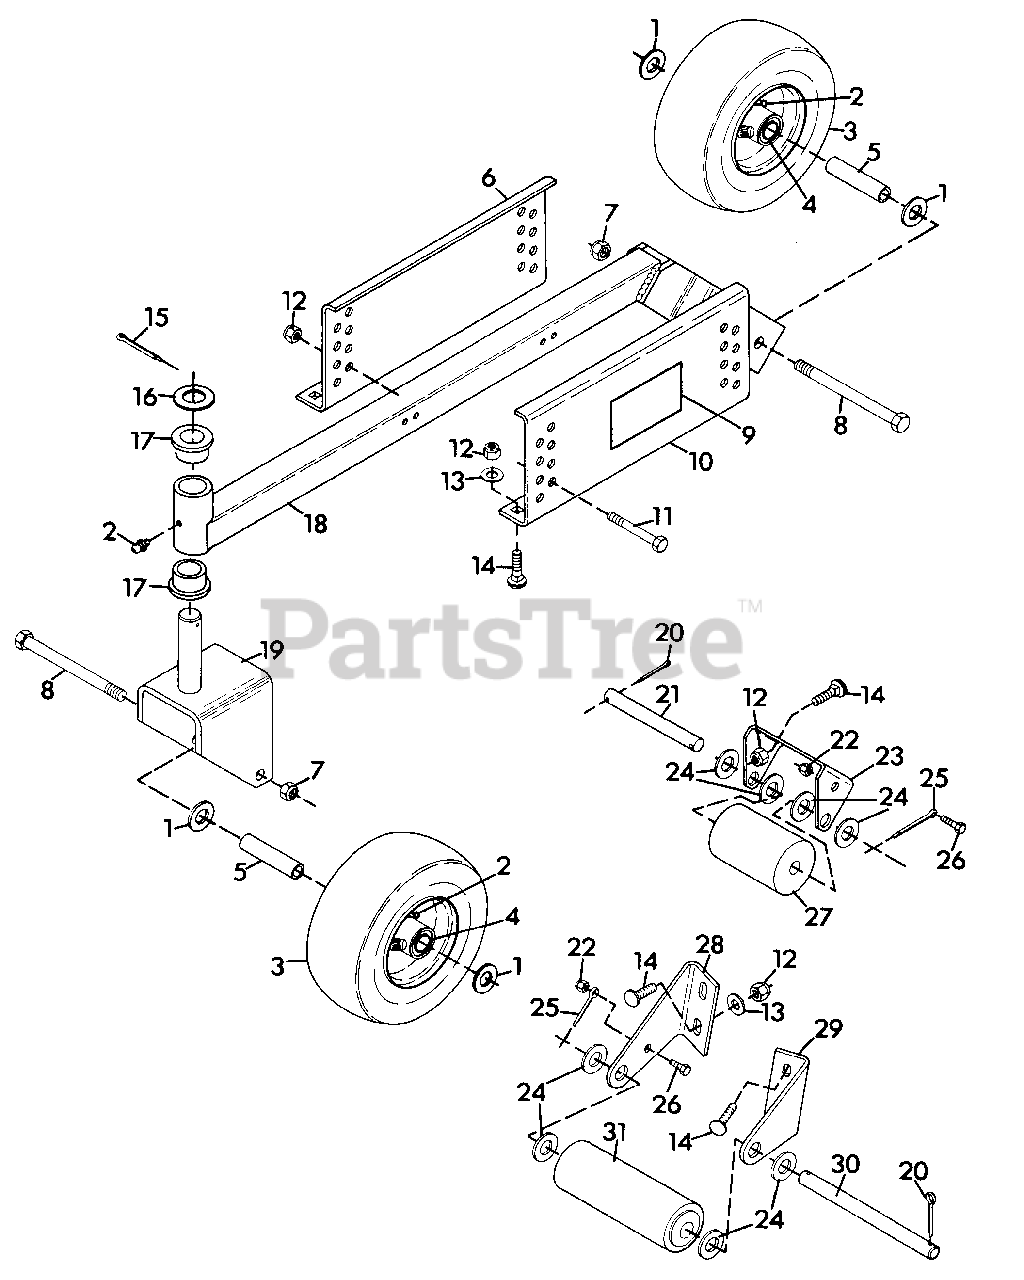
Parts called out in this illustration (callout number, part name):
1	Washer-Flat-Steel .531 x 1.250 x .100
2	Fitting-Lube .25-28 x .256
3	Wheel 9 x 3.50
4	Bearing, Gauge Wheel
5	Spacer .532 x.748 x 3.34
6	Hanger, Left Hand
7	Nut-Locking-Nylon .50-13 Grade 5
8	Bolt-Hex .50-13 x 5.00
9	Decal, Danger Foot
10	Hanger, Right Hand
11	Bolt-Hex .38-16 x 2.50 Grade 5
12	Nut-Locking-Nylon .375-16 Grade 2
13	Washer-Flat-Steel .406 x .812 x .065
14	Bolt-Round Head Square Neck .38-16 x 1.0
15	Pin-Cotter .188 x 1.625
16	Washer-Hardened-Thrust 1.002 x 1.552 x .030
17	Bushing-Flange 1.020 x 1.385 x .75 x 1.75
18	Weldment, Caster Wheel Support
19	Weldment, Caster Fork
20	Pin-Cotter .25 x 1.00
21	Rod
22	Nut-Hex .250-20 Grade 2
23	Bracket, Roller
24	Washer-Flat-Steel .656 x 1.312 x .095
25	Pin-Cotter .250 x 2.00
26	Bolt-Hex .25-20 x .75 Grade 5
27	Roller, Gage
28	Bracket, Roller Right Hand
29	Bracket, Roller Left Hand
30	Shaft, Center Roller
31	Roller, Gage
